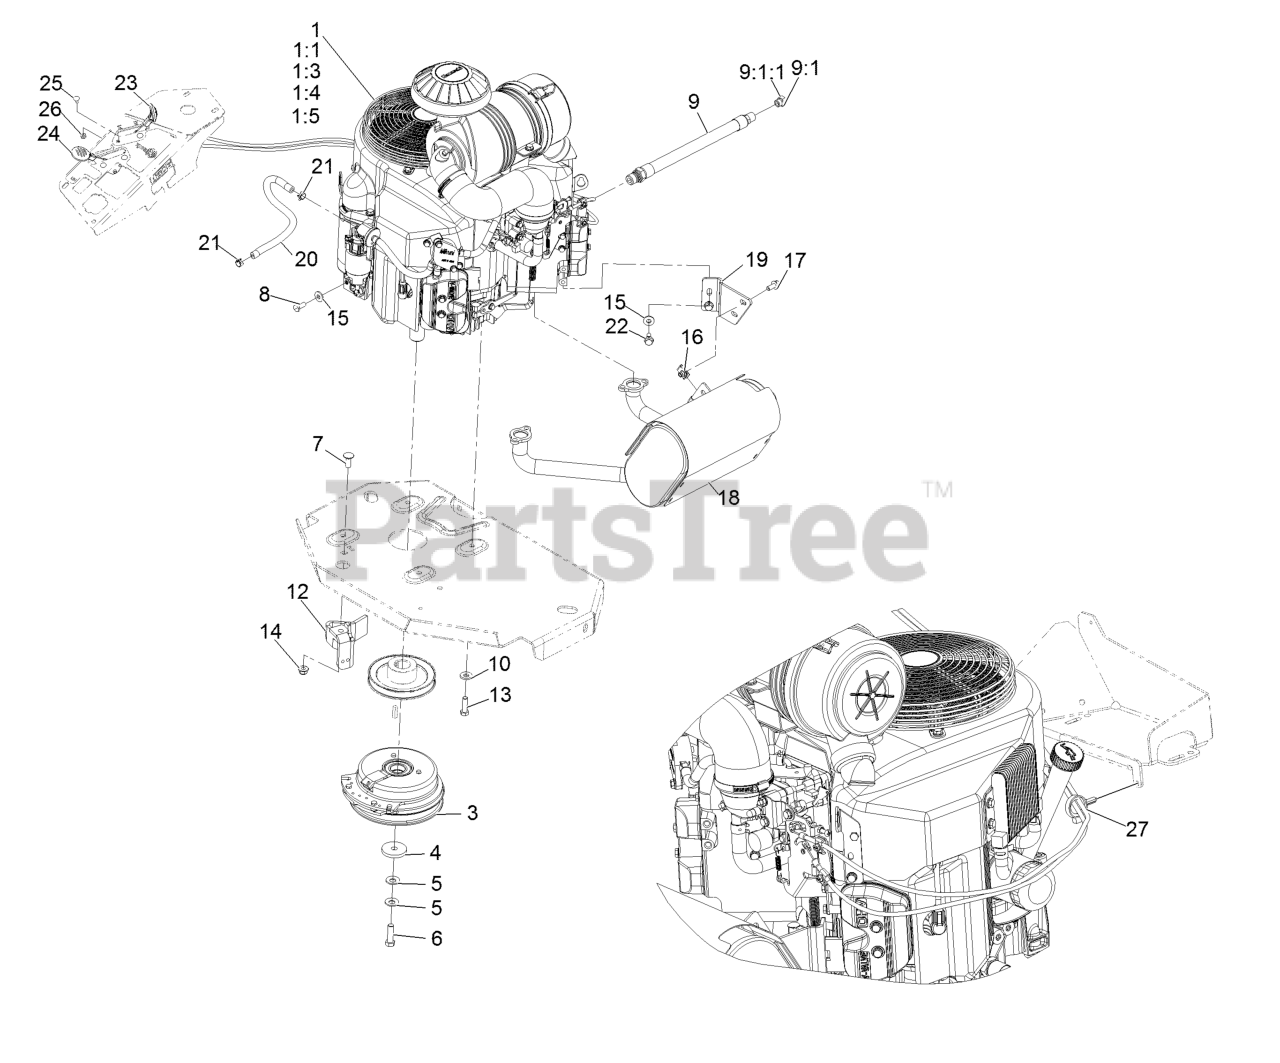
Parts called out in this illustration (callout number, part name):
1:1	Kawasaki 49065-2078 Engine Oil Filter
1:3	Kawasaki 49019-7001 Fuel Filter
1:4	Kawasaki 11013-7039 Safety Filter
1:5	Kawasaki 11013-7038 Air Filter
3	Clutch Kit
4	Washer-Clutch
5	Washer-Spring Disc 7/16
6	Screw-HH 7/16-20 X 1 1/2 W/Loctite
7	Bolt-Carriage 3/8-16 X 1
8	Screw-HH M8-1.25 X 20Mm
9	Asm-Hose Oil Drain W/Plug
9:1	Plug-W/O-Ring
9:1:1	O-Ring
10	Washer-Spring Disc 3/8
12	Clutch-Anchor
13	Screw-HH 3/8-16 X 1 1/4
14	Nut-Nyloc 3/8-16 Flg
15	Washer-Spring Disc 5/16
17	Screw-HH Flg 5/16-18 X 3/4
18	Muffler
19	Bracket-Muffler
20	Hose-Fuel Line 15"
21	Clamp-Hose
22	Screw-HH M8-1.25 X 20Mm
23	ASM, Choke Cable
24	ASM,Throttle Cable
25	Bolt-Carriage #10-24 X 1/2
26	Nut-Nyloc #10-24
27	Clamp-Hose
